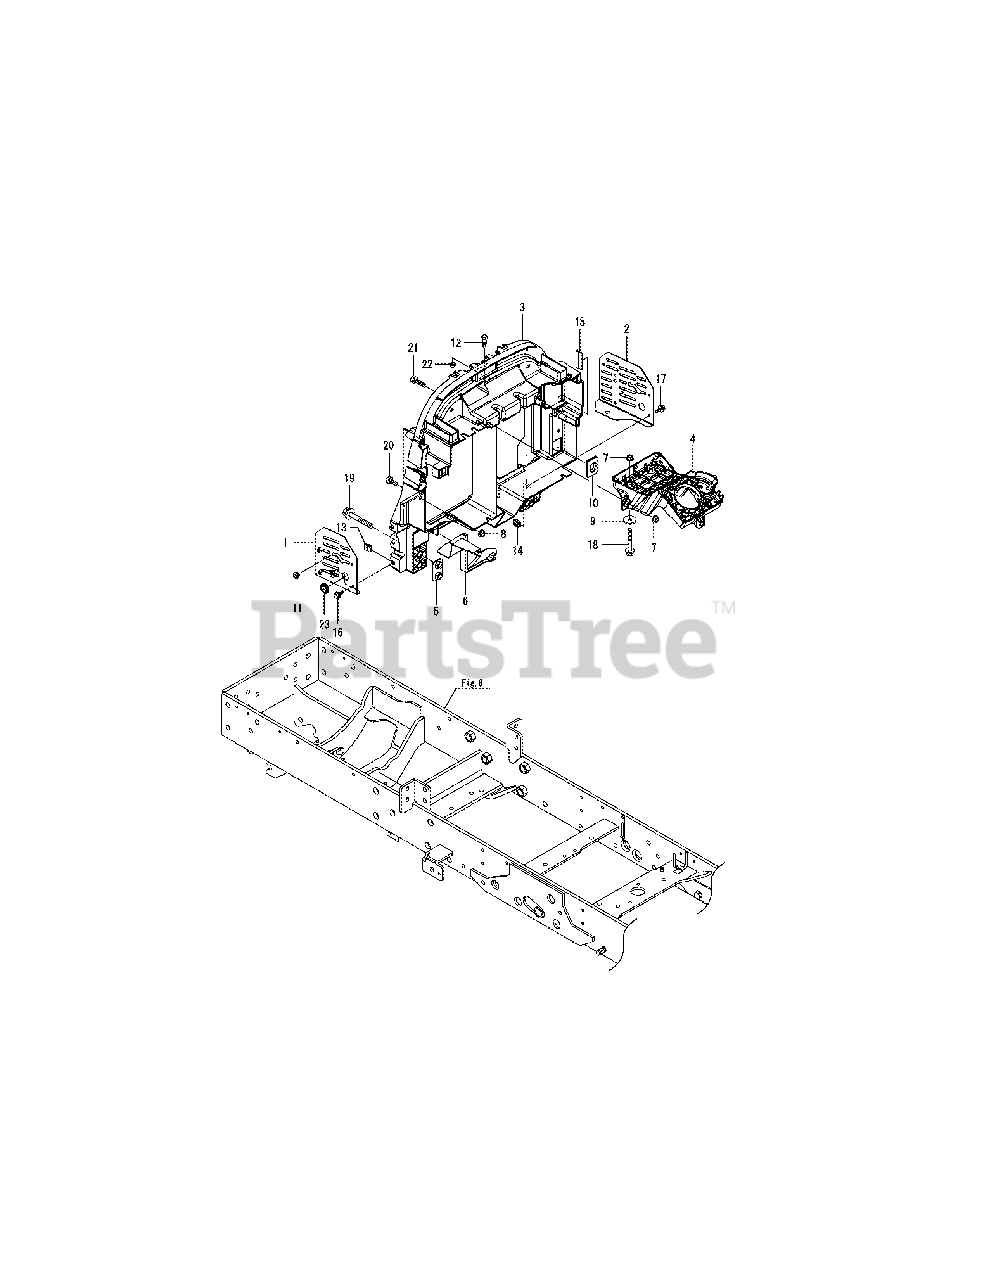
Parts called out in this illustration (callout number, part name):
1	COVER ASSY, LH, FAN BELT
2	COVER ASSY, RH, FAN BELT
3	BRACKET, COLUMN
4	BRACKET, STEERING
6	BOOT, DASHCOVER
7	NUT W/WASHER 8
8	NUT W/WASHER 8
9	WASHER 9X32X3.2
10	GROMMET, HARNESS
16	BOLT M 6X 16 PLATED
17	BOLT M 6X 16 PLATED
18	BOLT M 8X 65 PLATED
19	BOLT M10X 75 PLATED
20	BOLT M 8X 20 PLATED
21	BOLT M 8X 40 PLATED
23	GROMMET 16.0X2.0
